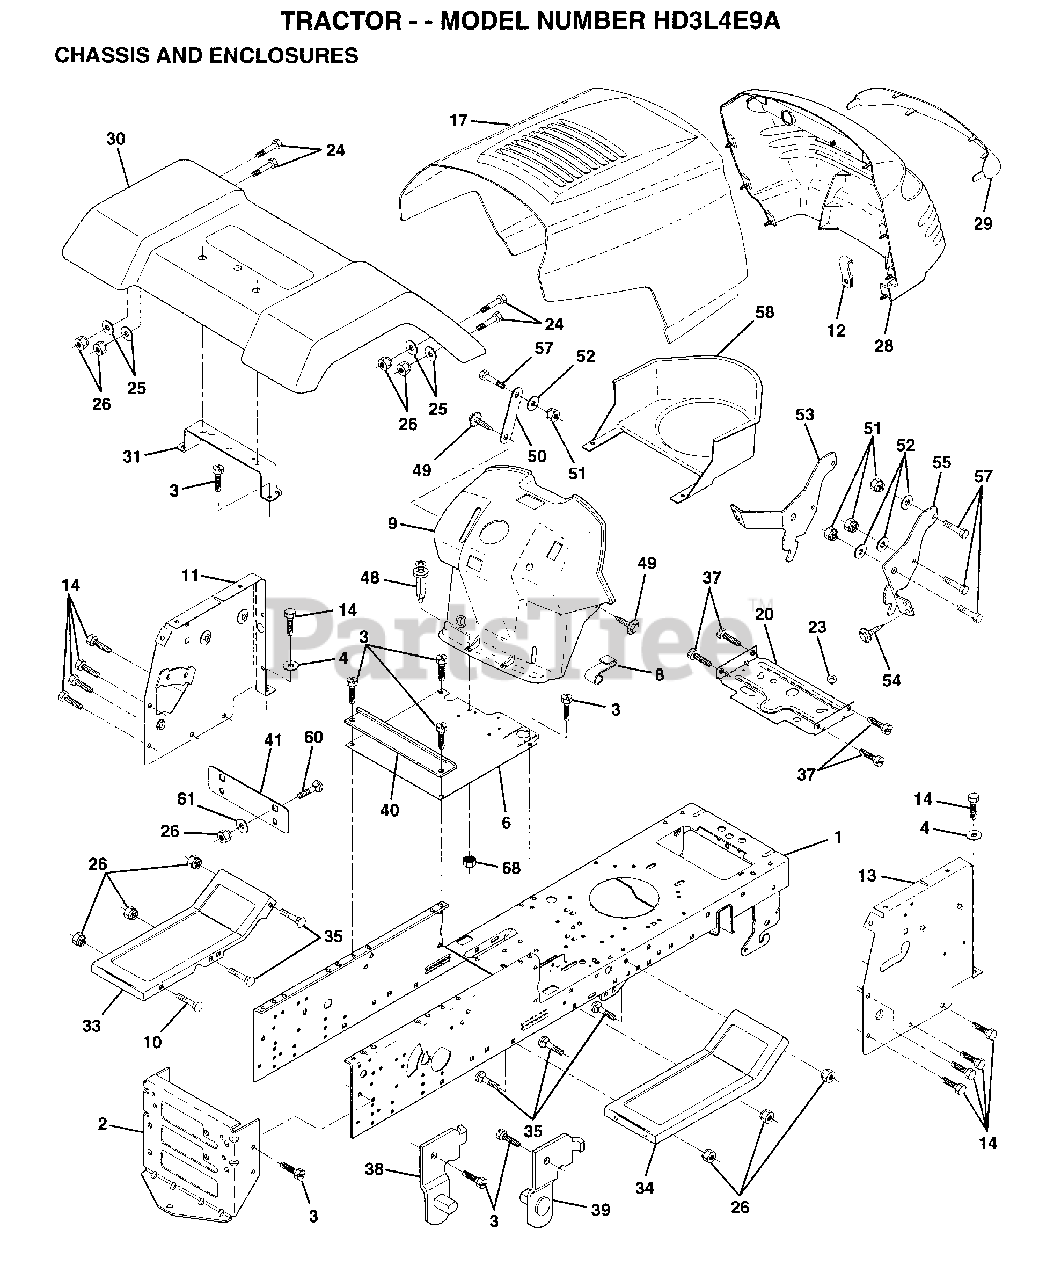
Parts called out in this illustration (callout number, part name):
1	CHASSIS.WLD.11GA
3	SCREW
4	WASHER
8	"CLIP,INSULATOR"
11	PANEL.DASH.LH.
12	CLIP.TINNERMAN
13	PANEL.DASH.RH
14	SCREW LT
20	PLATE.MTG.BTRY.TK
24	BOLT
25	WASHER
26	NUT
29	LENS GRILLE
31	BRACKET SUPT FEND
33	FOOTREST.LH.LT/GT
34	FOOTREST.RH.LT/GT
35	BOLT
37	SCREW LT
38	BRACKET ASM LH
39	BRACKET ASM RH
40	SPACER FENDER LT
41	PLATE EXTEN FEND
48	RIVET.PUSH.PLATE
49	SCREW HEX CRT
50	BRACE SUPT DASH
51	NUT
52	WASHER
53	BRACKET.GRILLE.LH
55	BRACKET.GRILLE.RH
58	DUCT.AIR.B&S.18HP
60	BOLT
61	WASHER
68	NUT
